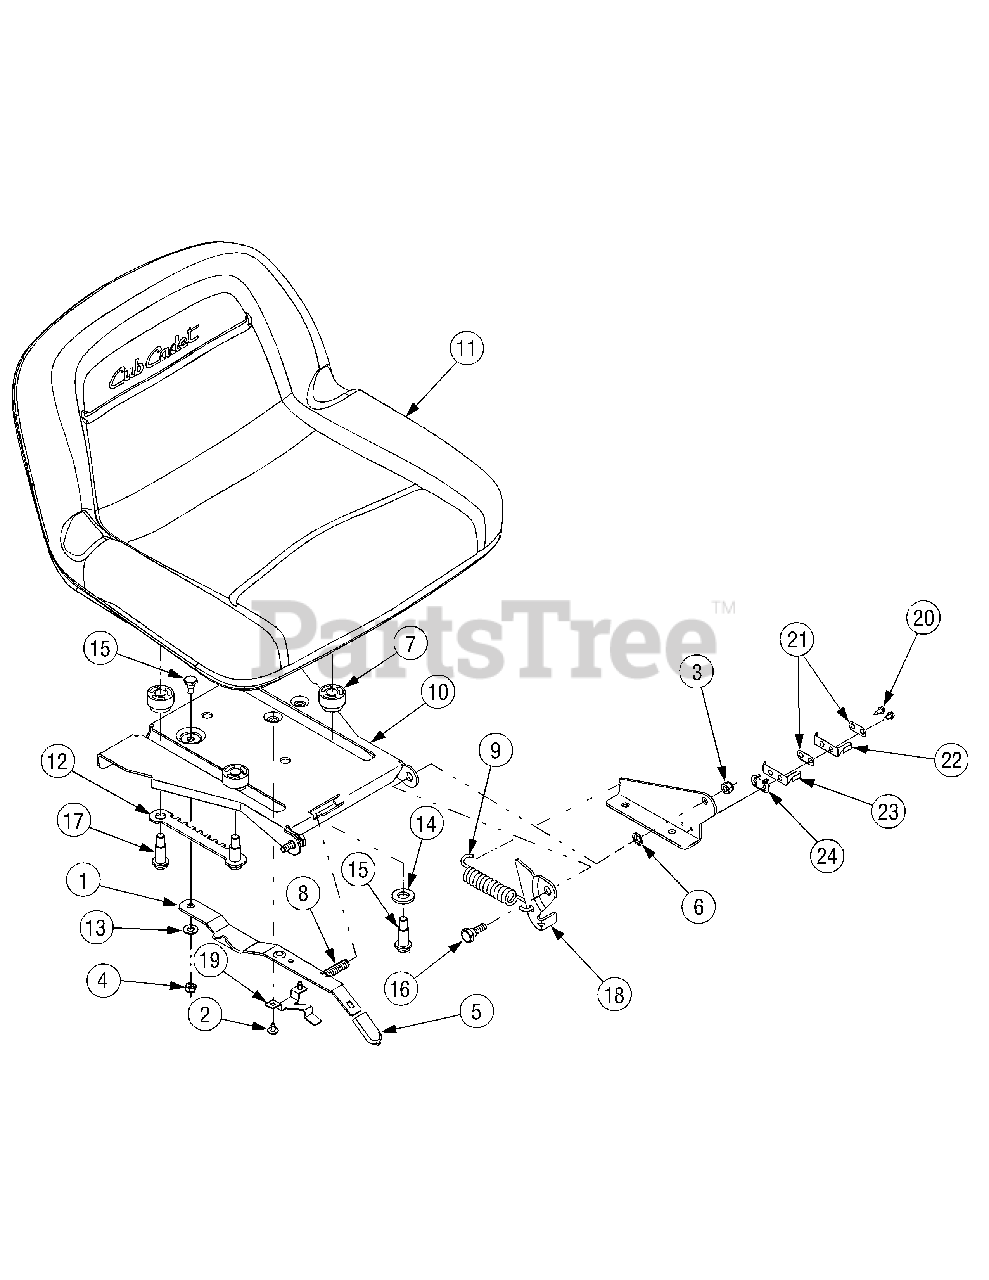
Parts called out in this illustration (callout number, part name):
2	Screw, #10-16, 0.375
3	Nut, Nylon Lock, 5/16-18, Gr5
4	Nut, Nylon Lock, 1/4-20 GrF
5	Grip, Seat, Adjustment (Yellow)
6	Nut, Speed, .3125 ID
7	Spacer, Seat, Adjustment
8	Spring, Compression .41 x 1.50
9	Spring, Extension, .80 Dia x 4.6
11	Seat, Cub Cadet, High Back, Bead
11	Seat, Cub Cadet, Medium Back, Bead
11	Seat, High Back, Black
12	Selector, Seat, Adjustment
13	Washer, Flat, .344 x ..620 x .033
14	Washer, Flat, .531 x 1.062 x .134
15	Screw, Shlder, .340 x .285, 1/4-20
16	Shoulder, Screw .437 x .286 Lg
17	Screw, Shoulder, .50 x.925, 3/8-16
18	LH Bracket, Seat Lift
19	Stop, Seat, Adjustment
20	Screw, #8-18 x .50
21	Plate, Insulator
22	Spring Switch, Outer
23	Spring Switch, Inner
24	Plate, Insulator Boss
